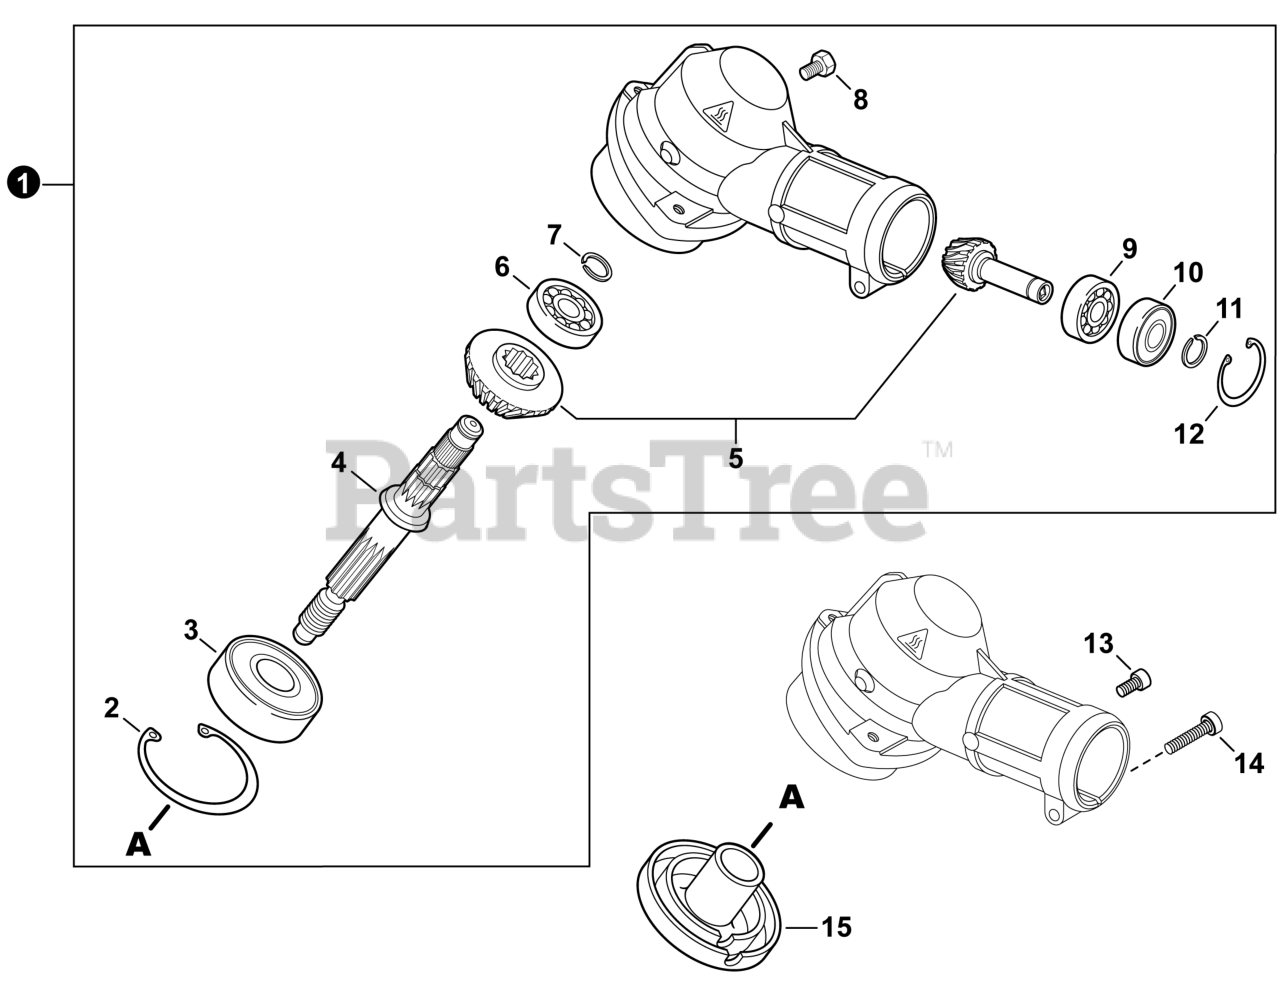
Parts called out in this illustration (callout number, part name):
1	GEAR CASE ASSY
2	RING, SNAP 42
3	BEARING, BALL 6302
4	SHAFT, GEAR
5	GEAR SET
6	BEARING, BALL 629
7	RING, SNAP 12
8	BOLT M8x8
9	BEARING, BALL 609
10	BEARING, BALL 609
11	RING, SNAP 9
12	RING, SNAP 25
13	BOLT, TORX 5x12
14	BOLT, TORX 5x25
15	PLATE, ADAPTOR - UPPER
